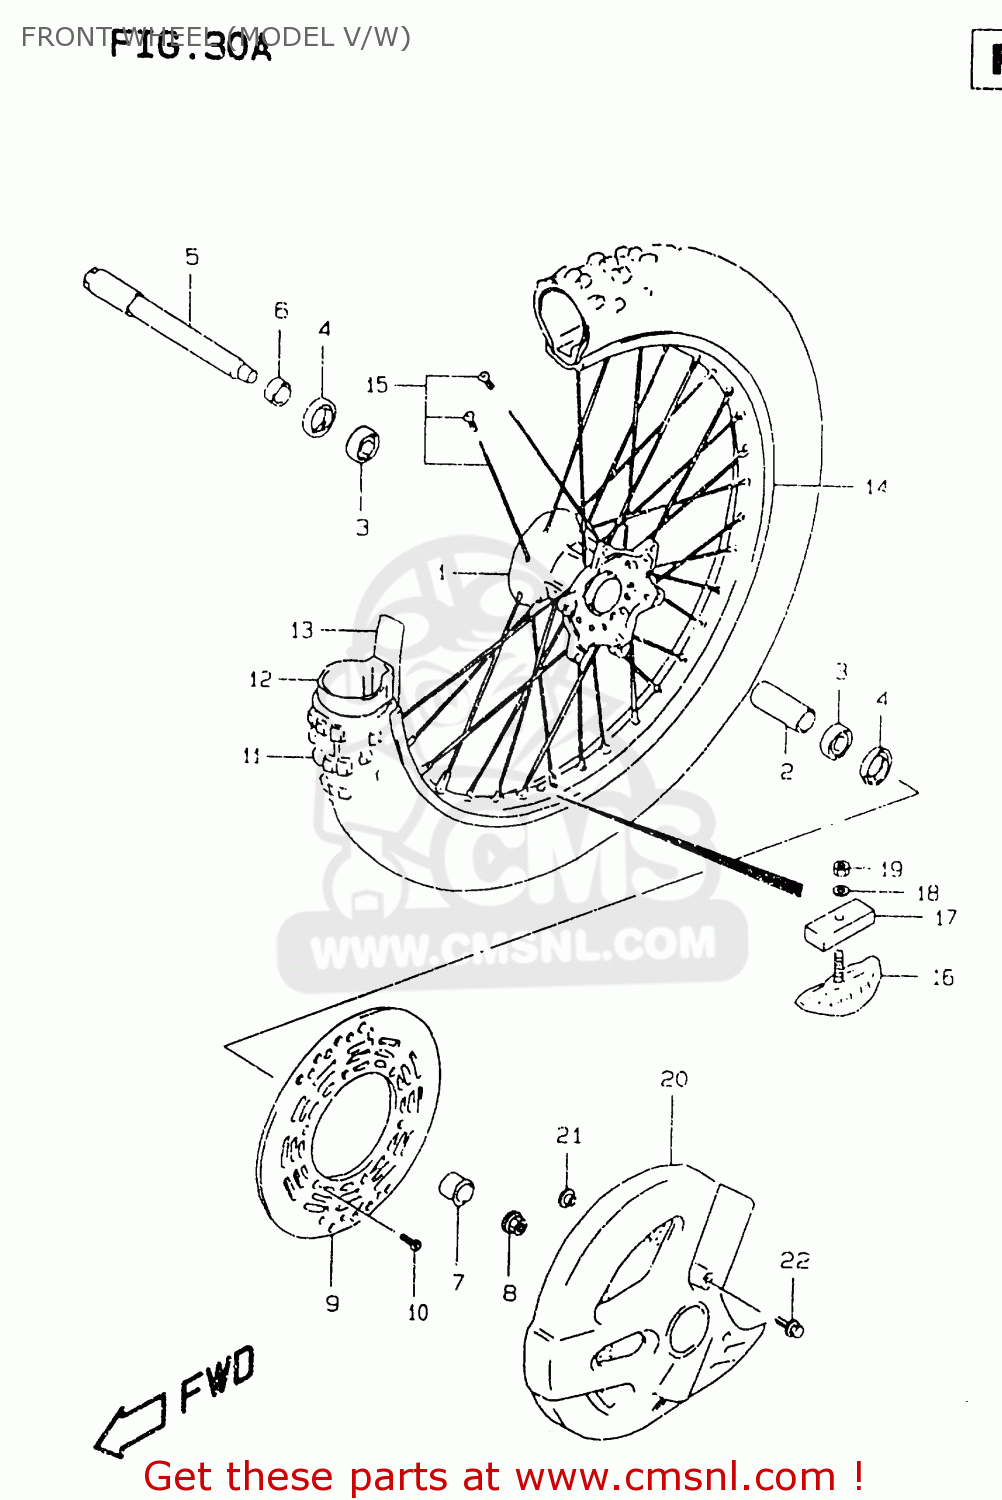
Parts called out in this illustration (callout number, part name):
1	HUB,FR
2	SPACER,FR HUB BEARING
3	BEARING
4	SEAL,OIL(25X37X6)
5	AXLE,FRONT
6	SPACER,FR AXLE,R
7	SPACER,FR AXLE,L
8	NUT
9	DISC,FR BRAKE
10	SCREW
11	TIRE, FR 80/100
12	TUBE
13	PROTECTOR,WHEEL INNER
14	RIM,FR WHEEL(1.60X21 AL)(.WHT)
15	SPOKE SET,FR WHEEL
16	STOPPER,BEAD
17	CUSHION,BEAD STOPPER
18	WASHER
19	NUT
20	COVER,FRONT BRAKE DISC
21	WASHER
22	BOLT(6X16)
